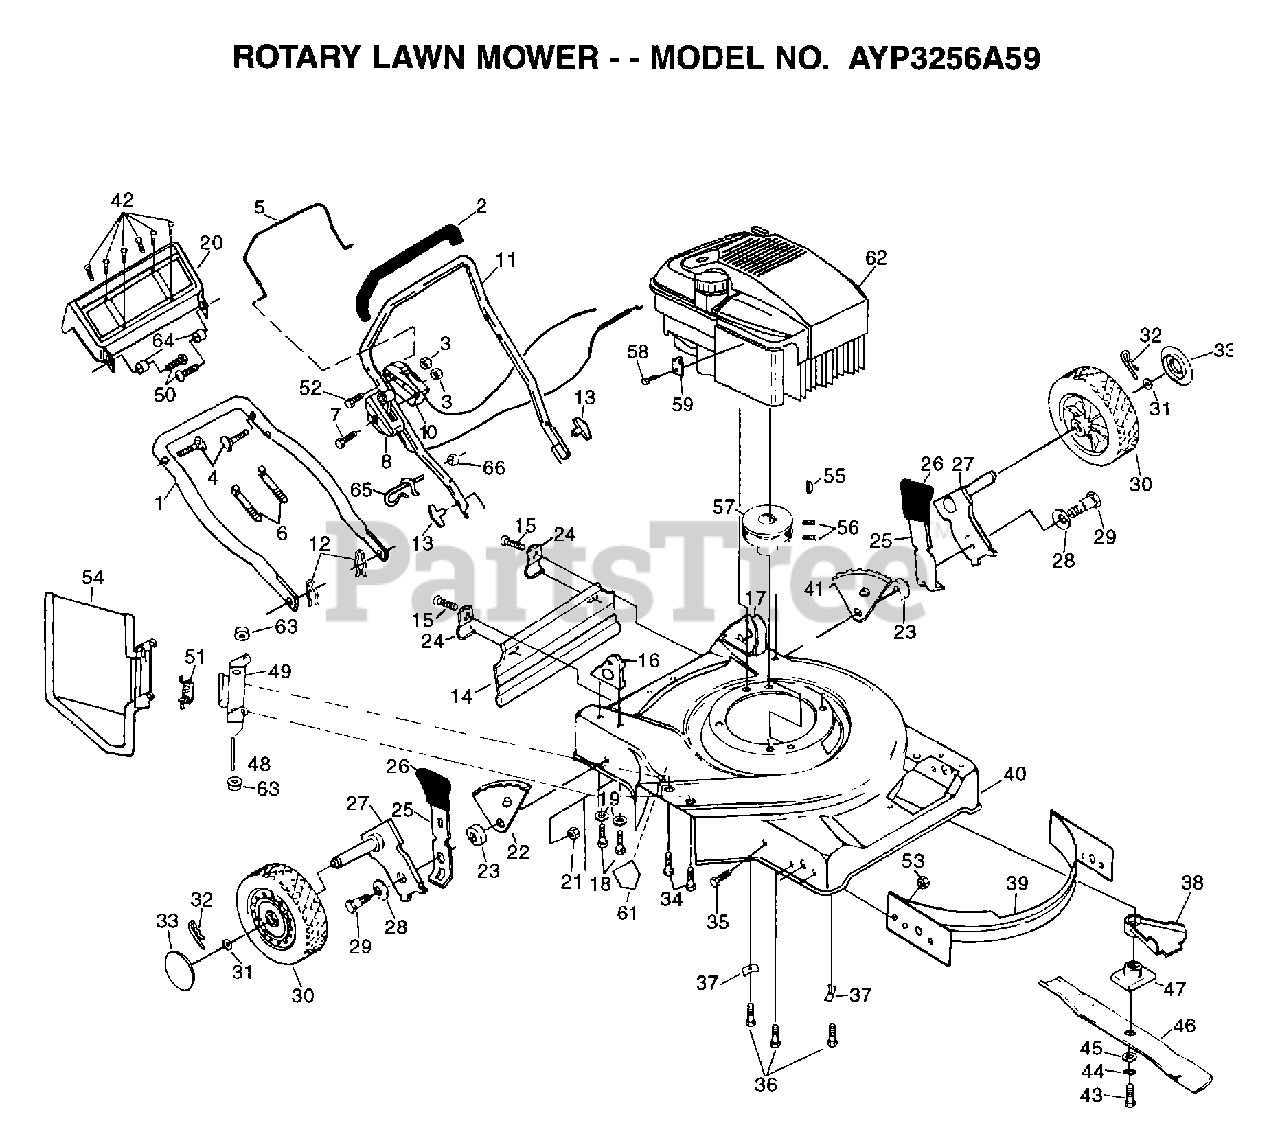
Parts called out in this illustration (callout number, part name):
1	LOWER HANDLE
4	BOLT.HANDLE.LM
5	CONTROL BAR
7	SCREW.1/4-20X3.00
8	"CONTROL, THROTTLE"
10	CONTROL.ENG.E/S
12	HAIRPIN COTTER
13	KNOB HANDLE
14	SKIRT.REAR.22SD.
15	TAPPING SCREW
18	SCREW
19	STEEL WASHER
21	LOCKNUT PM
22	BRACKET ASM LF/RR
24	"BRKT,DEFL PM"
25	SELECTOR SPRING
27	AXLE ARM
28	"WASHER, BELLEVIL."
29	BOLT SHLD 3/8-16
31	WASHER
32	RETAINER CLIP PM
33	HUB CAP
34	SCREW
35	SCREW
36	SCREW
39	BAFFLE FRONT 22SD
40	KIT.HSG.22SD.FWGD
41	BRACKET ADJ LR/RF
42	SCREW SELF TAP
43	SCREW
44	LOCKWASHER
45	"WASHER,HARDEN"
46	"BLADE.MULCH.22"""
47	ADAPTOR.BLADE.LM
48	"ROD,HINGE "
49	"BRKT,HSG"
50	SCREW
51	"SPRING,TORSION"
52	SCREW.HXHD.WASH.
55	HI PRO KEY PM
56	SCREW
57	ENGINE.PULLEY.FWG
58	CABLE CLAMP
59	SCREW PM
61	DECAL-DANGER PM
63	PUSH ON SPEED NUT
64	NYLON BUSHING PM
65	ROPE GUIDE
66	NUT
